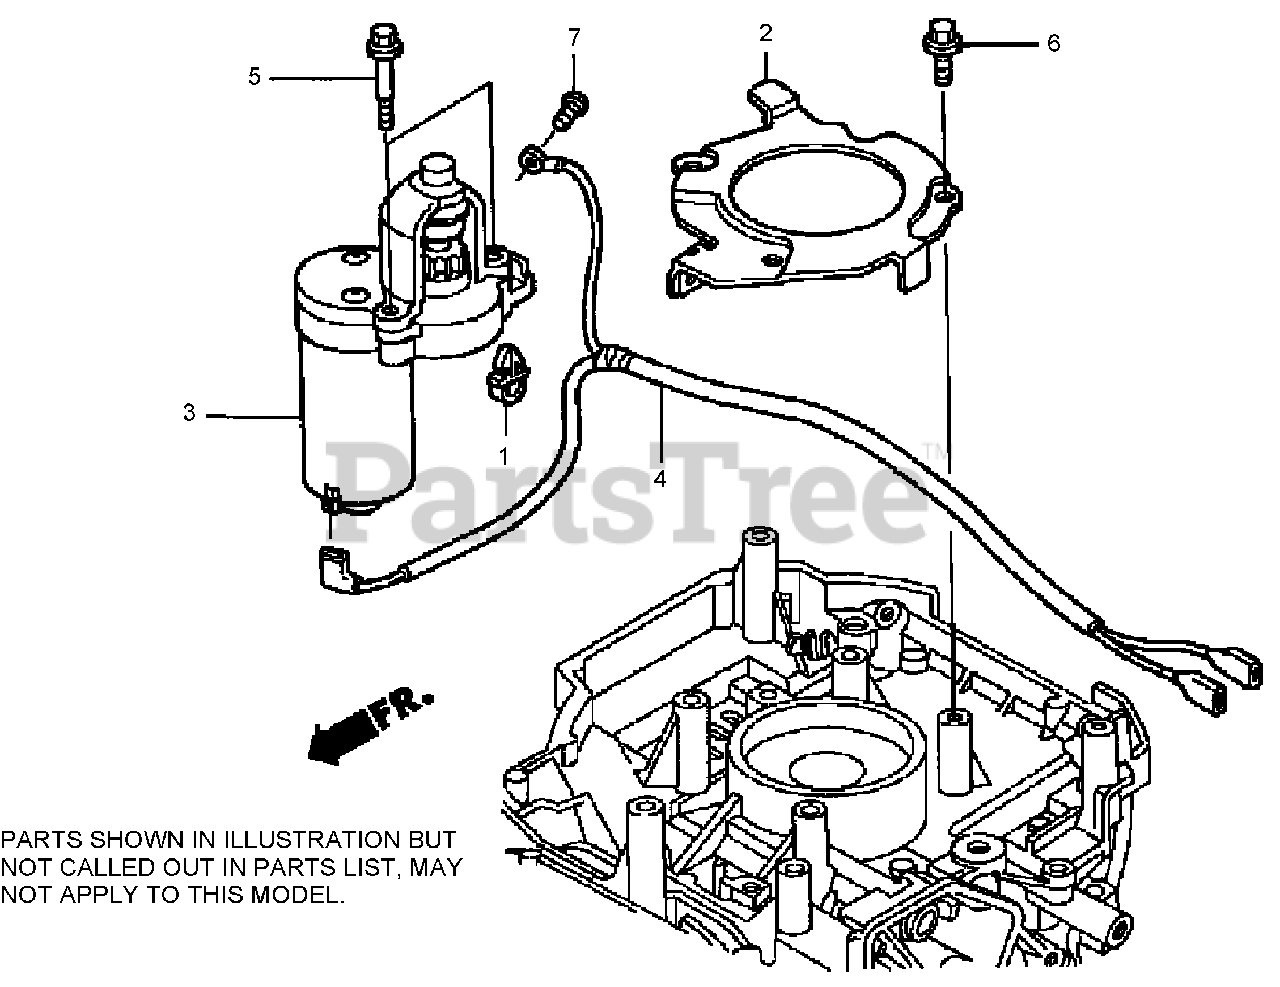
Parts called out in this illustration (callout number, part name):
1	HOLDER, WIRE
2	CLAMP, WIRE
3	MOTOR ASM., STARTER
4	WIRE, TERMINAL GROUND
5	BOLT, SPECIAL (6MM)
6	BOLT-FLANGE (6X12)
7	SCREW, PAN (5X8)
